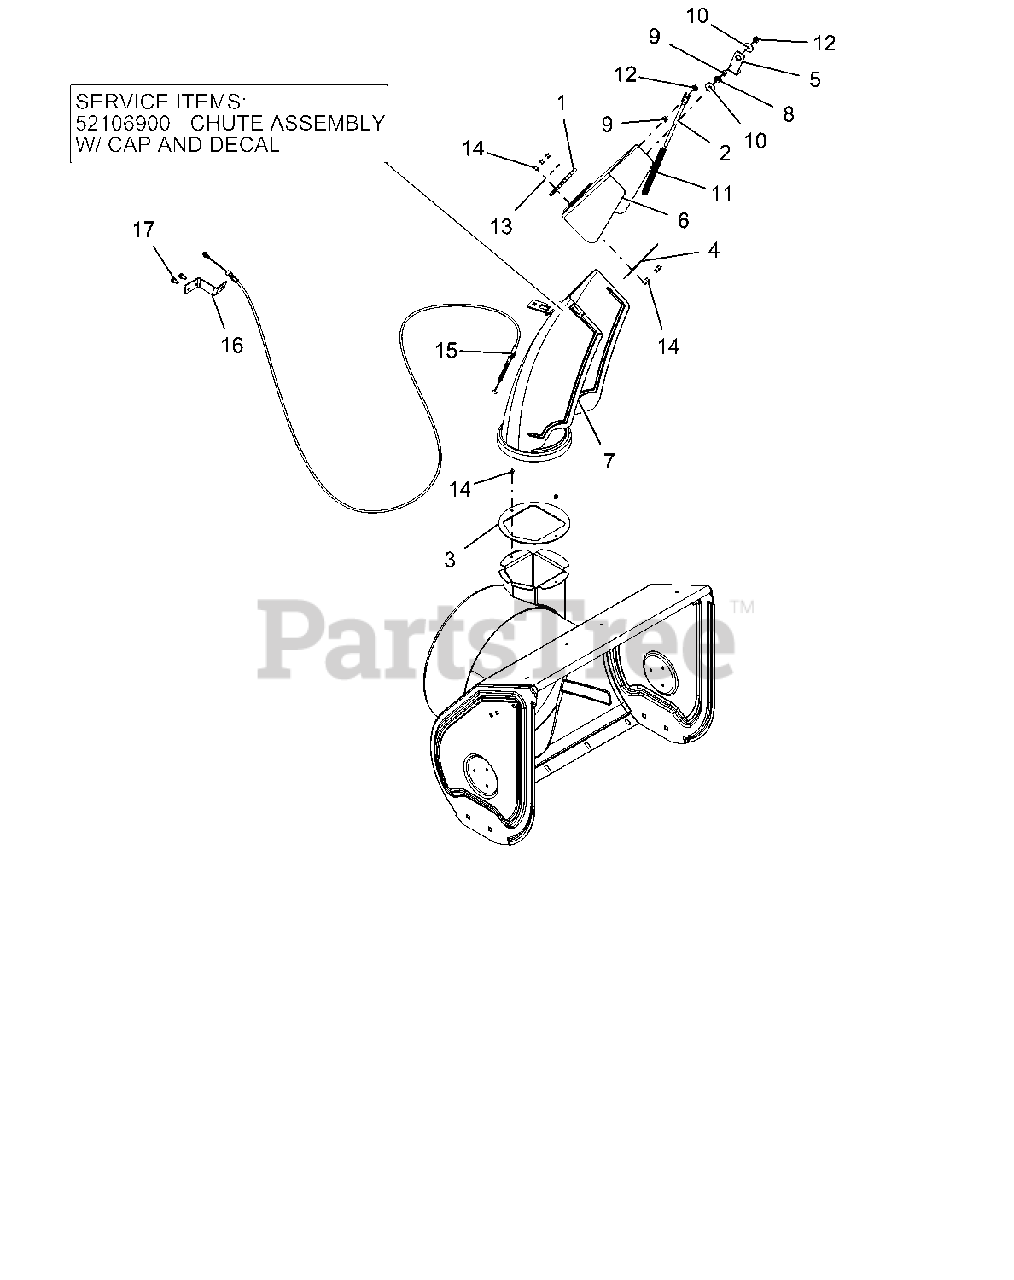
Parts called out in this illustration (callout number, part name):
2	ROD, DEFLECTOR CAP
3	BAFFLE, DISCHARGE NECK
4	CAP SEAL 5.50
5	BRACKET, CABLE ANCHOR
6	CAP,LARGE,REMOTE
7	KIT, DISCHARGE CHUTE W/DEF ID
8	BUSHING, POLYLINER-.50 SNAPIN
9	BSHG-SLV .265X.500X.219
10	WSHR-FL-STL .281X1.000X.063
11	SG-COMP .08X.40X6.50 14#/IN
12	@NUT-LK-CTR-FLG .25-20 YWZC
13	WSHR-FL-STL .196X.500X.06 YZ
14	RVT-POP .187 YZ
15	CABLE, DEFLECTOR - DELUXE
16	ANCHOR, DEFLECTOR CABLE
17	SCR-TAP .25-20X.50 HWH TR YWZ
